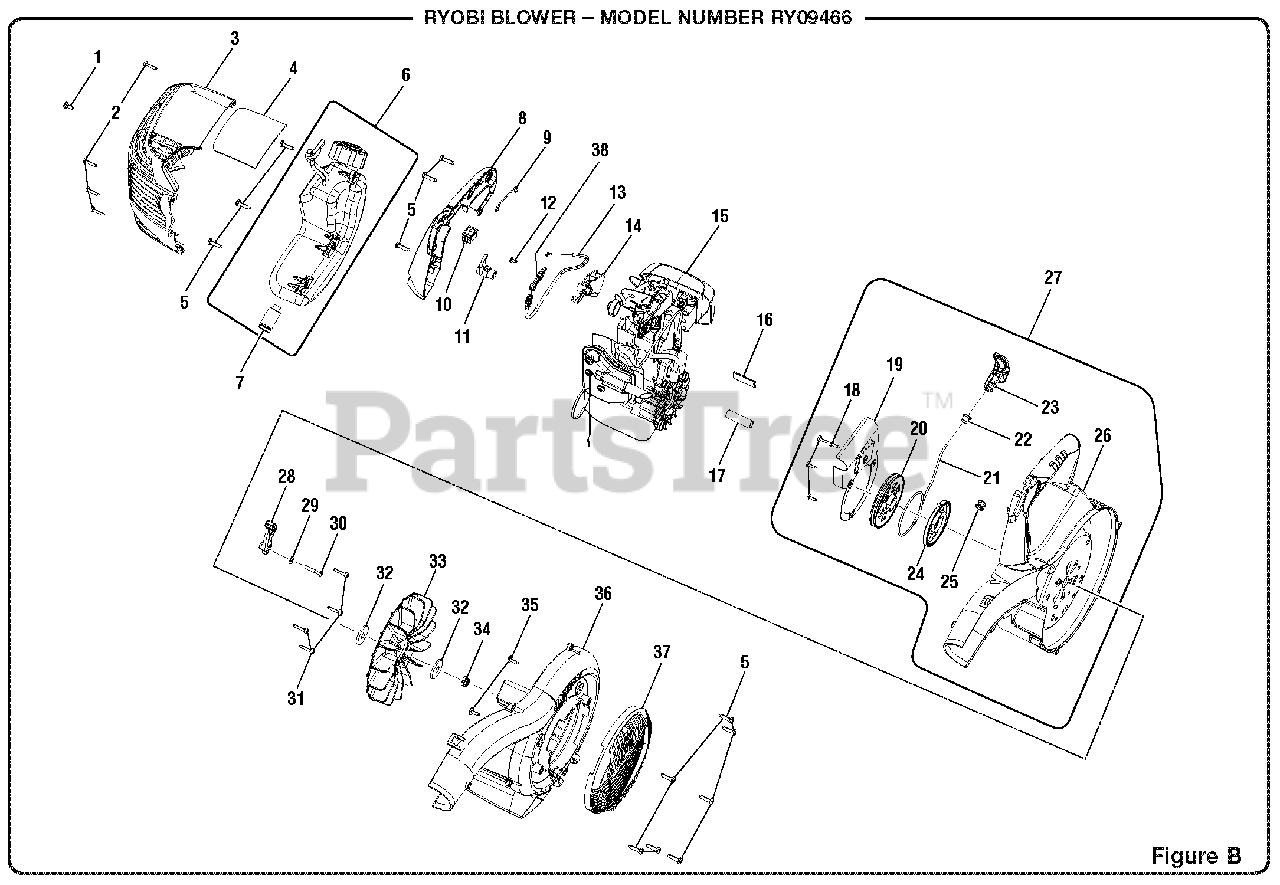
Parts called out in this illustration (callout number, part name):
1	Screw (M5 x 10.5 mm, T20 Torx Hd. )
2	Screw (M4 x 18 mm, T20 Torx Soc. Hd.)
3	Engine Housing
4	Heat Shield
5	Screw (#10-14 x 3/4 in, T25 Torx Pan Hd. T.F.)
6	Fuel Tank Assembly w/Cap
7	Fuel Filter
8	Handle Cover
9	Ground Wire
11	Trigger Lock
12	Screw (M3.5 x 7.5 mm, T20 Torx Pan Hd.)
13	Throttle Cable
15	Power Head Assembly
18	Screw (M4 x 12 mm, T20 Torx Truss Hd.)
20	Starter Pulley
21	Starter Rope
23	Starter Grip
24	Container Spring Assembly
26	Inner Volute
27	Lower Housing w/Starter
28	Cruise Lever
29	Washer (ID4.3 x OD12 x 1.5t)
30	Cruise Lever Screw (M8-14 x 25 mm, Special T20 Truss Hd.)
31	Screw (M4 x 23 mm, T20 Truss Hd. T.F.)
32	Washer (ID9.8 x OD34.27 x 2.28t)
33	Fan
34	Lock Nut (3/8 in.)
35	Screw (#10-14 x 1/2 in., T25 Torx Truss Hd.)..
36	Outer Volute
37	Air Inlet Cover
38	Throttle lever
